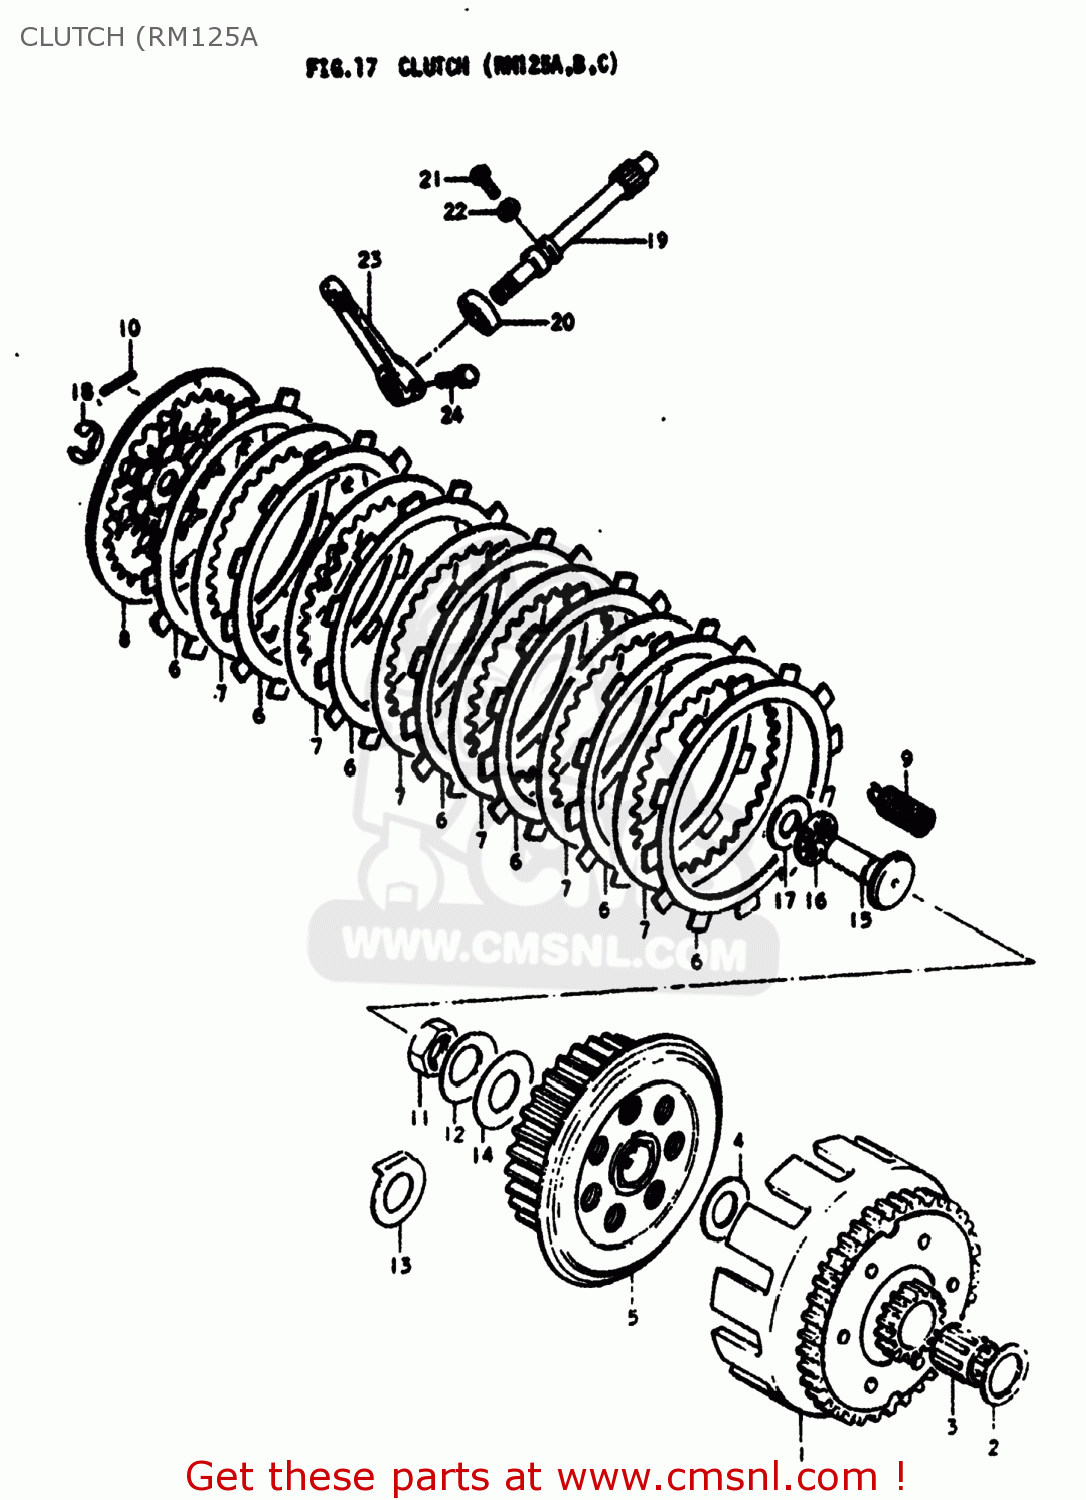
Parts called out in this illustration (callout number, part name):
1	GEAR ASSEMBLY,PRIMARY DRIVE
2	WASHER
3	BEARING(20X25X26)
4	WASHER
5	HUB,CLUTCH SLEEVE
6	PLATE,CLUTCH DRIVE
7	PLATE,CLUTCH DRIVEN
8	PLATE,CLUTCH PRESSURE
9	SPRING
10	PIN(2.5X19.8)
11	NUT
12	WASHER
13	WASHER,LOCK
14	WASHER
15	RACK,CLUTCH RELEASE
16	BEARING(10X22X2.8)
17	WASHER
18	E RING 8MM
19	PINION,CLUTCH RELEASE
20	SEAL,OIL (10X17X5)
21	BOLT(6X12)
22	WASHER
23	ARM,CLUTCH RELEASE
24	BOLT, UPPER
